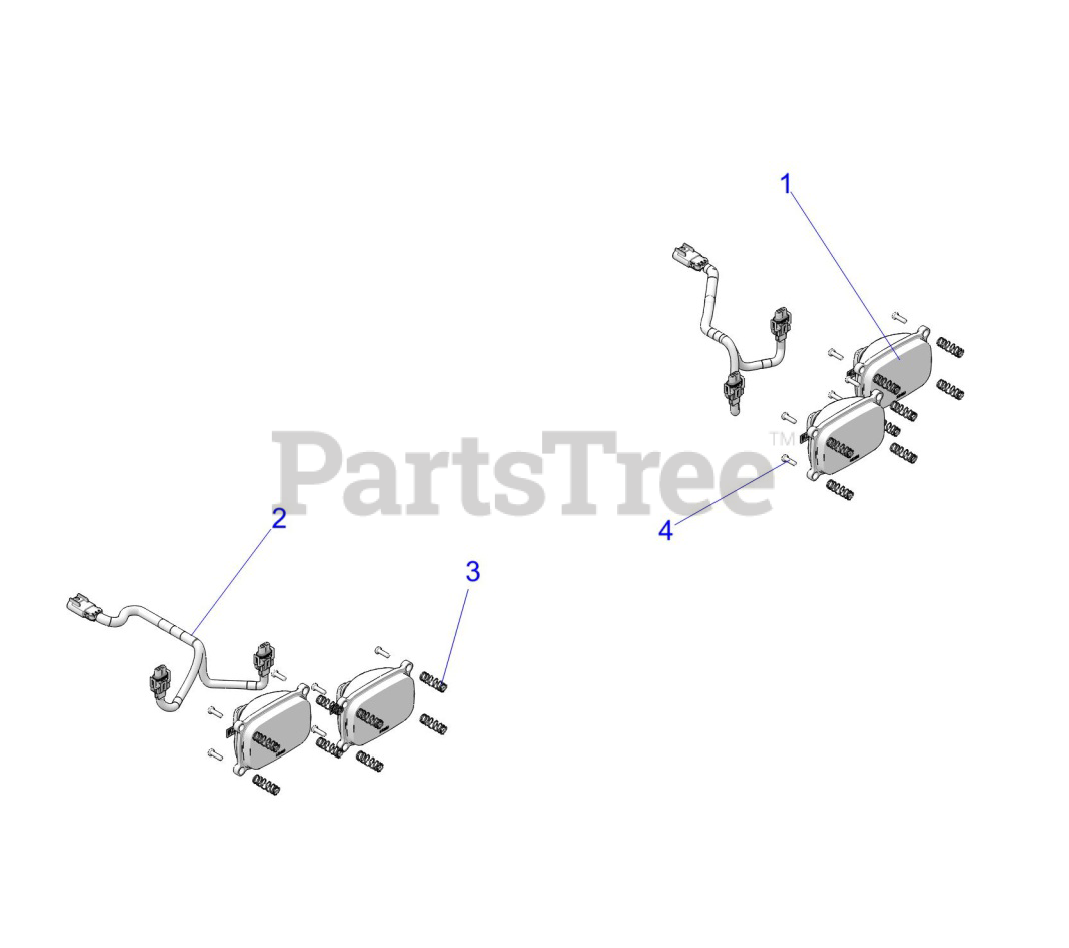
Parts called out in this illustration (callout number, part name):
1	ASM-HEADLIGHT
2	HARNESS-HEADLIGHT,ARNS
3	SPRING, HEADLIGHT
